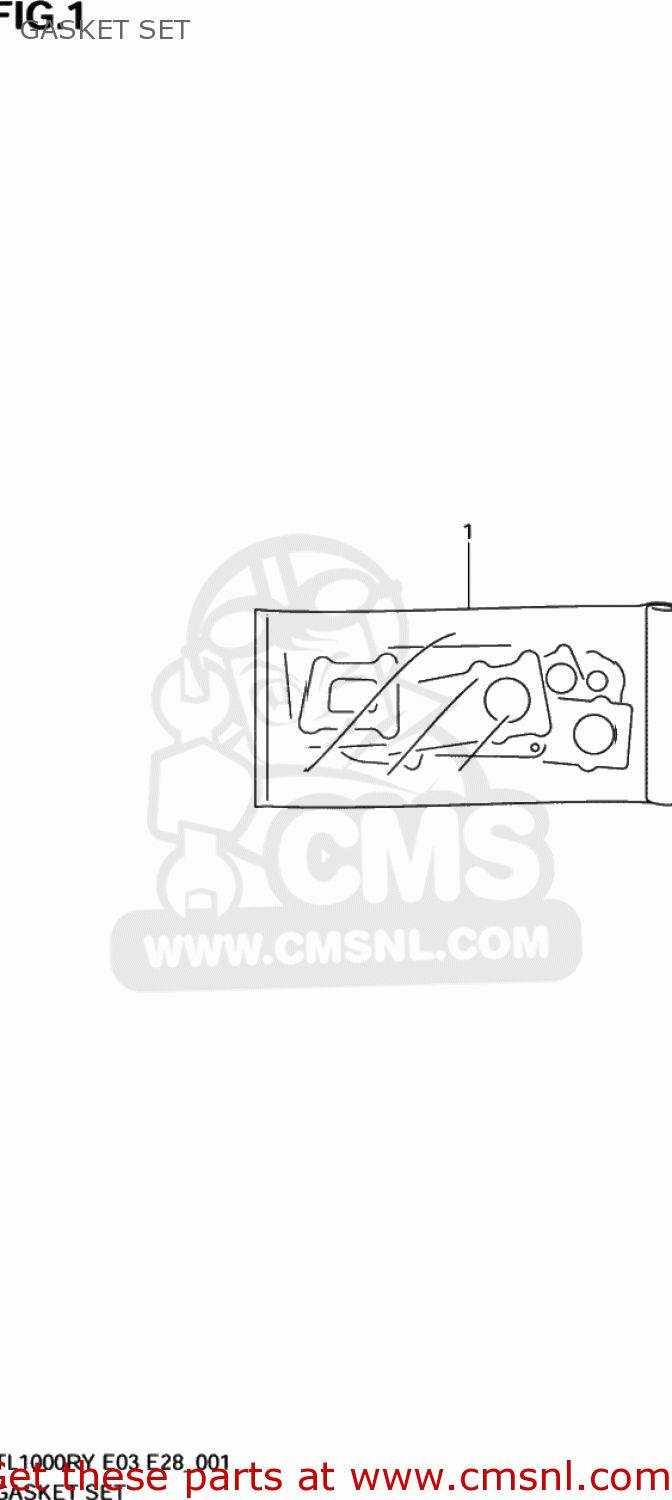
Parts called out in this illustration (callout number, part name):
1	GASKET SET (NAS)
2	GASKET,CYLINDER HEAD (NAS)
3	GASKET,CYL HEAD COVER NO.1 (NAS)
4	GASKET,CYL HEAD COVER NO.2
5	GASKET,CYLINDER FR (NAS)
6	GASKET,CYLINDER RR (NAS)
7	GASKET,CLUTCH COVER (NAS)
8	GASKET,MAGNETO COVER (NAS)
9	O RING,CLUTCH COVER OUTER
10	GASKET,GEAR SHIFT COVER (NAS)
11	GASKET,TENSIONER ADJUSTER (NAS)
12	GASKET,TENSIONER ADJUSTER (NAS)
13	GASKET,UNION BOLT (NAS)
14	GASKET,MUFFLER JOINT (NAS)
15	GASKET,EXHAUST PIPE (NAS)
16	WASHER(10.6X25.5X2.3)
17	GASKET(5.8X11X1.2) (NAS)
18	O RING(D:2.4,ID:55.6)
